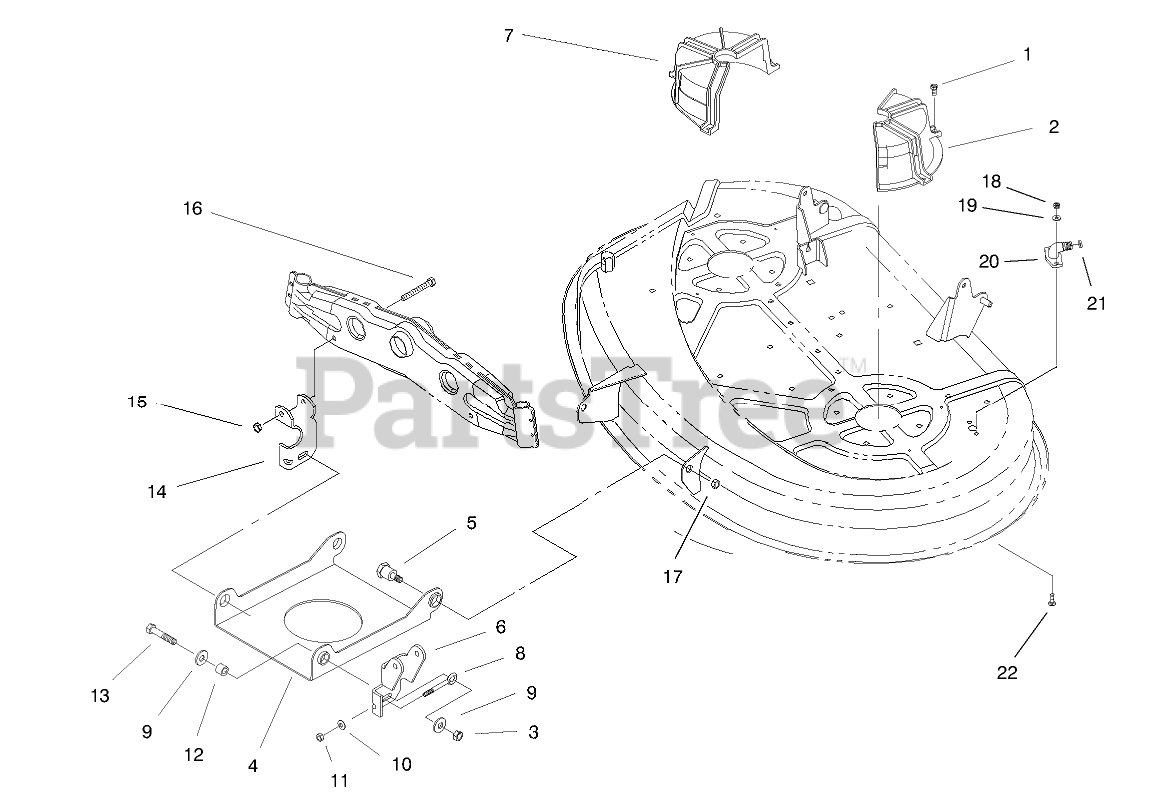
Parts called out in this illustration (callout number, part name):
1	SCREW-HWHTF
2	GUIDE-BELT, LH
3	NUT-LOCK, NI
4	PAN-DECK SUSPENSION, FRONT
5	BOLT-SHOULDER, HH
6	BRACKET-SUSPENSION, LH
7	GUIDE-BELT, RH
8	SCREW-ADJUSTING
9	WASHER-HARDENED
10	WASHER-FLAT
11	NUT-LOCK, NI
12	SPACER
13	SCREW-HH
14	BRACKET-SUSPENSION, RH
15	NUT-LOCK, NI
16	SCREW-HH
17	NUT-LOCK, NI
18	NUT-LOCK, NI
19	WASHER-FLAT
20	FITTING-WASHOUT
21	O-RING
22	BOLT-CARR
